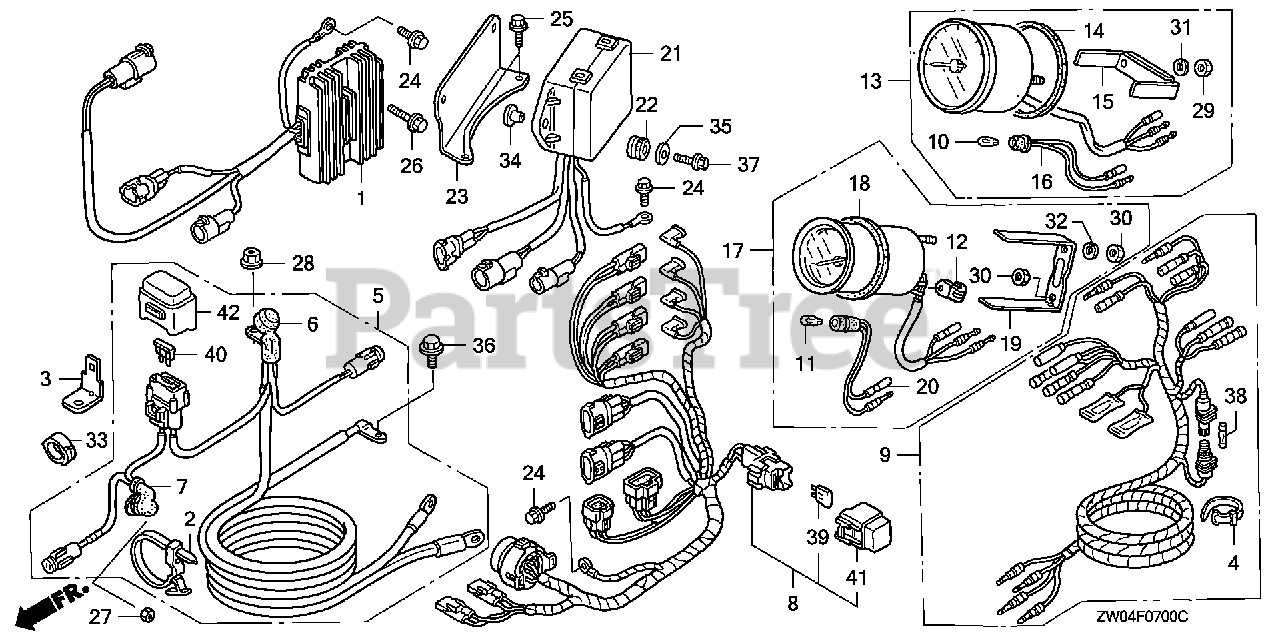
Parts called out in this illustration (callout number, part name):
1	RECTIFIER ASSY., REGULATOR (20A)
2	BAND, WIRE
3	BRACKET, FUSE
4	BAND B1, CABLE
5	CABLE ASSY., STARTER
6	COVER, STARTER TERMINAL
7	COVER, MAGNETIC SWITCH TERMINAL
8	CABLE ASSY., REMOTE CONTROL (A)
9	HARNESS ASSY., METER (A)
10	BULB, WEDGE BASE (12V1.7W) (NIPPON SEIKI)
11	BULB, WEDGE BASE (12V1.7W) (TOSHIBA)
13	TACHOMETER ASSY.
17	METER ASSY., TRIM
21	RELAY ASSY., POWER TILT
22	GROMMET, RELAY
23	BRACKET, RELAY
24	BOLT, FLANGE (6X12)
25	BOLT, FLANGE (6X14)
26	BOLT, FLANGE (6X22)
27	NUT, HEX. (6MM)
28	NUT-WASHER (8MM)
29	NUT, HEX. (5MM)
30	NUT, HEX. (4MM)
31	WASHER, SPRING (5MM)
32	WASHER, SPRING (4MM)
33	CLIP, WIRE HARNESS
34	COLLAR, IGNITION CONTROL MODULE CASE
34	COLLAR, MODULE IGNITION CONTROL CASE (CDI)
35	WASHER, PLAIN (6MM)
36	BOLT, FLANGE (6X14)
37	BOLT, FLANGE (6X25)
38	FUSE A (10A)
39	FUSE, BLADE (15A)
40	FUSE, BLADE (30A)
41	COVER ASSY., FUSE (15A)
42	COVER ASSY., FUSE (30A)
